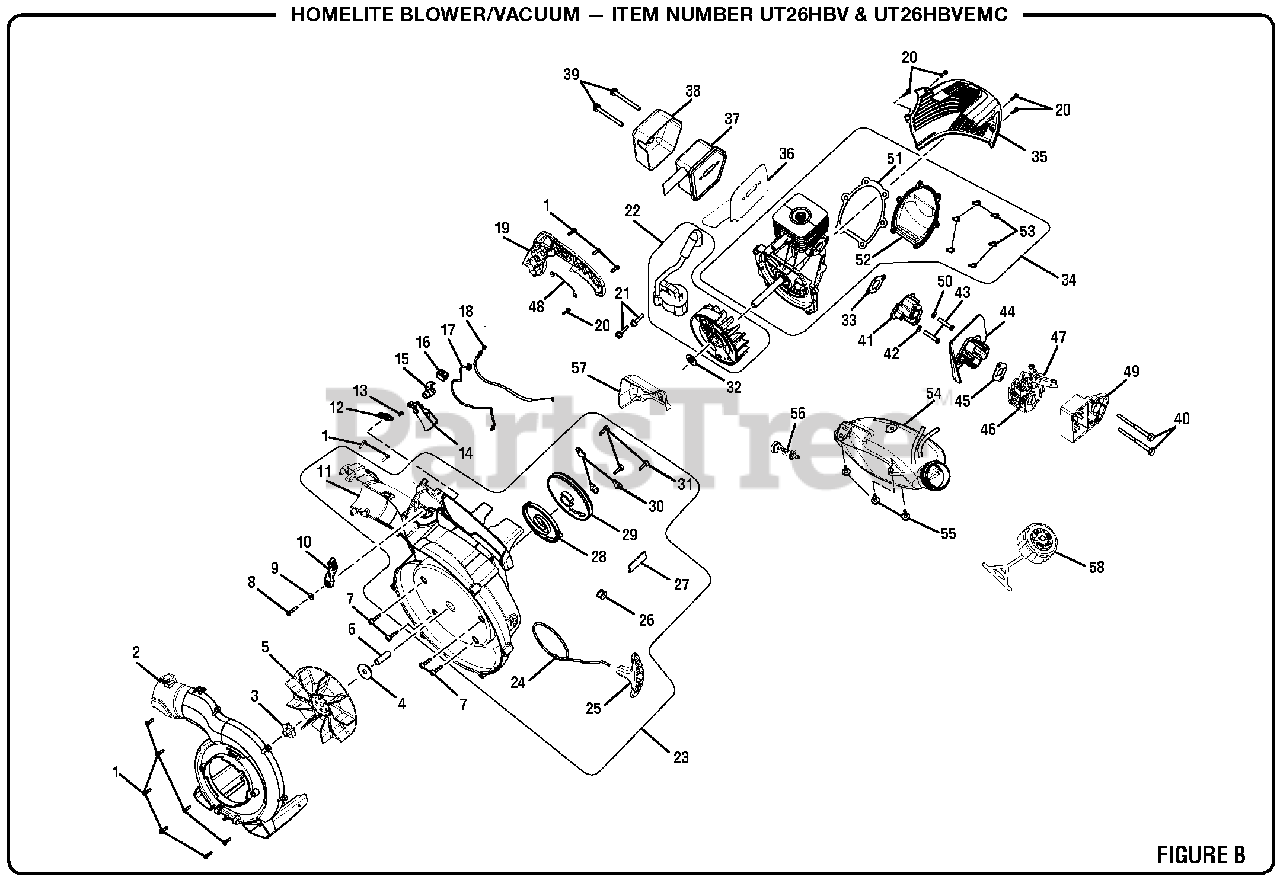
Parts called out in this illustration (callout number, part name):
1	Screw (10-14 x 3/4 in.)
2	Outer Volute w/Labels
3	Blower Fan Nut
7	Screw (M4 x 17 mm, T.F.)
8	Screw (8-14 x 1 in., T.F.)
10	Cruise Control Lever
11	Inner Volute w/Eyelet w/Label
12	Throttle Lever
13	Screw (M3.5 x 7.5 mm)
14	Throttle Trigger
15	Trigger Lock
16	Momentary Contact Switch
17	Wire Assembly (UT26HBV)
18	Throttle Cable
19	Handle Cover
20	Screw (M4 x 18 mm)
21	Screw (M4 x 19 mm, T.F.)
22	Ignition Module and Flywheel Kit (UT26HBV)
23	Lower Housing w/Starter and Label
24	Starter Rope (42 in.)
25	Starter Grip
28	Spring & Container
29	Starter Pulley
30	Pulley Retainer
31	Screw (M4 x 14 mm, T.F.)
33	Intake Gasket
34	Short Block Assembly
35	Engine Cover w/Labels
36	Muffler Gasket
37	Muffler Assembly
38	Muffler Heat Shield
39	Screw (10-24 x 2-1/8 in.)
40	Screw (M5 x 48 mm)
43	Screw (M5 x 25 mm)
45	Heat Dam Gasket
46	Carburetor
47	Primer Bulb
48	Ground Wire Kit
49	Air Box Base
51	Crankcase Cover Gasket
52	Crankcase Cover
53	Screw (M4 x 12 mm)
54	Fuel Tank w/Fuel Lines
55	Screw (M4 x 14 mm, Shoulder)
56	Fuel Filter
57	Baffle Plate
58	Fuel Cap w/Tether
